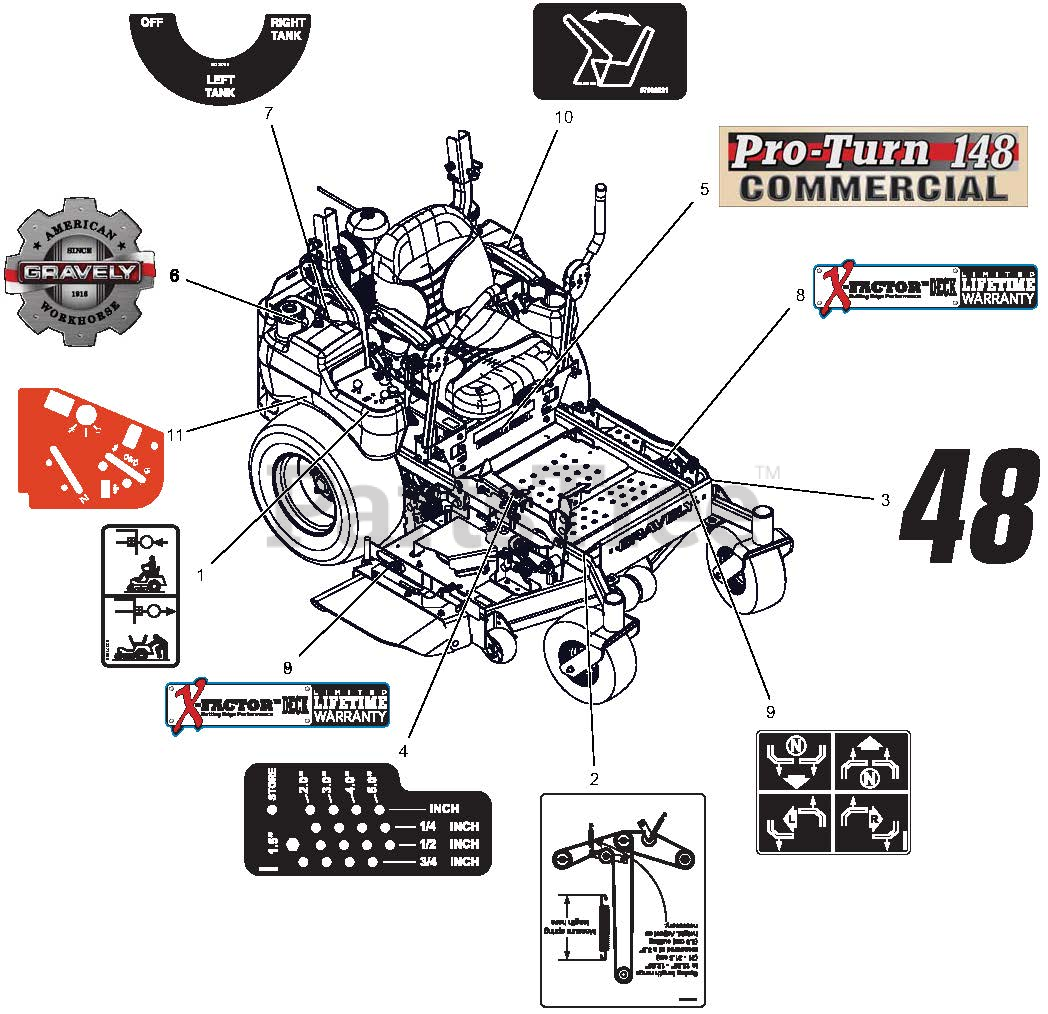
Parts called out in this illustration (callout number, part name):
1	DECAL, TRANSMISSION DISCONNECT
2	DECAL, BELT ROUTING
3	DECAL, 48"
4	DECAL, HEIGHT OF CUT
5	DECAL, PRO-TURN 148
6	DECAL, GRAVELY HERITAGE-LARGE
7	DECAL, FUEL VALVE
8	DECAL, X-FACTOR DECK
9	DECAL, INSTRUCTIONAL-STEERING
10	DECAL, SEAT RELEASE
11	PANEL, PT100 CONTROL
